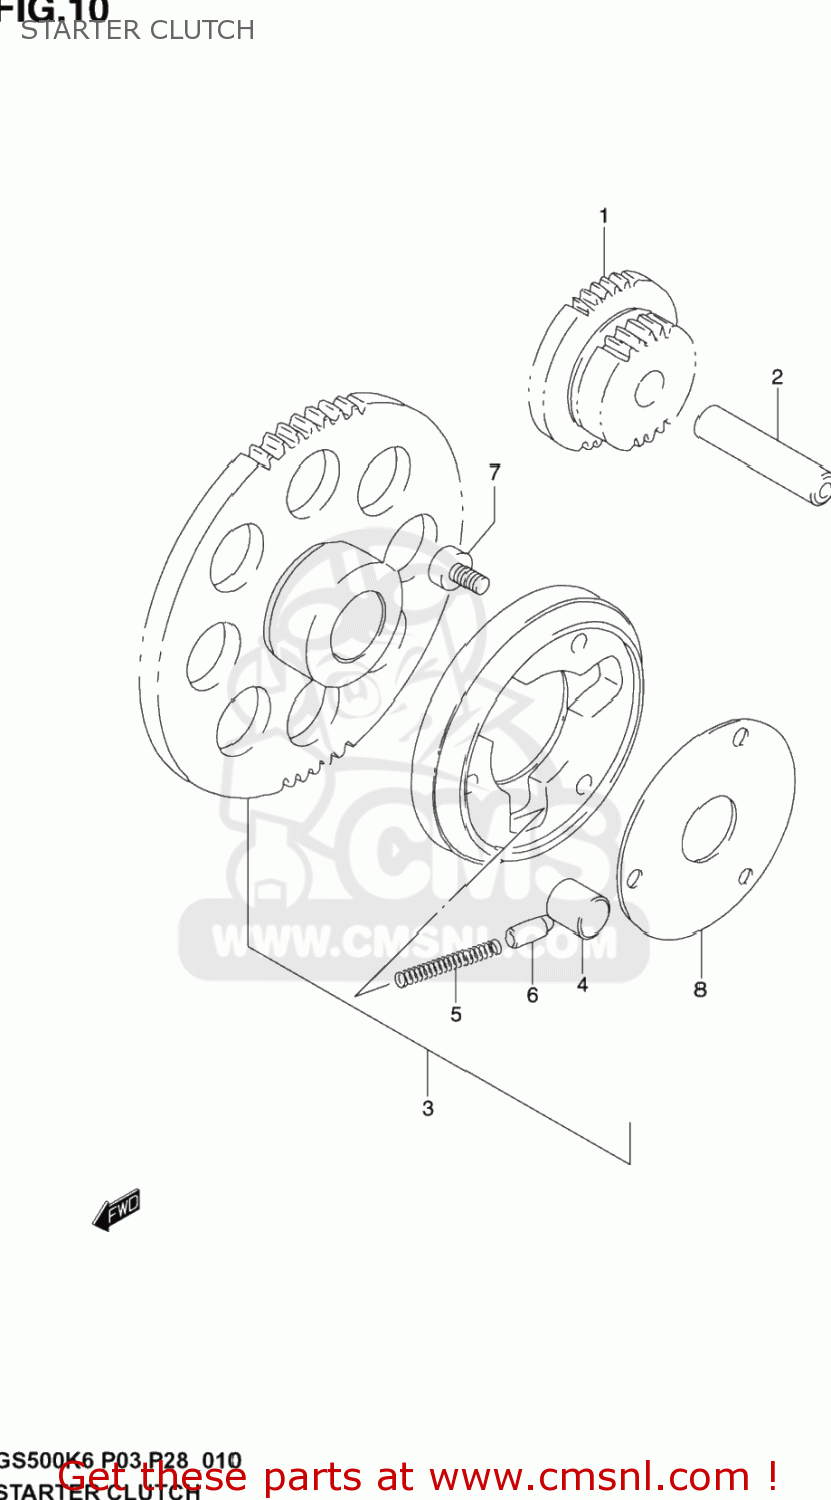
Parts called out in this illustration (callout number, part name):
1	GEAR,STARTER IDLE
2	PIN(7.4X13X56)
3	CLUTCH SET, STARTER
4	ROLLER(15X13)
5	SPRING
6	PIECE,PUSH
7	BOLT
8	SHIM,STARTER CLUTCH HUB
